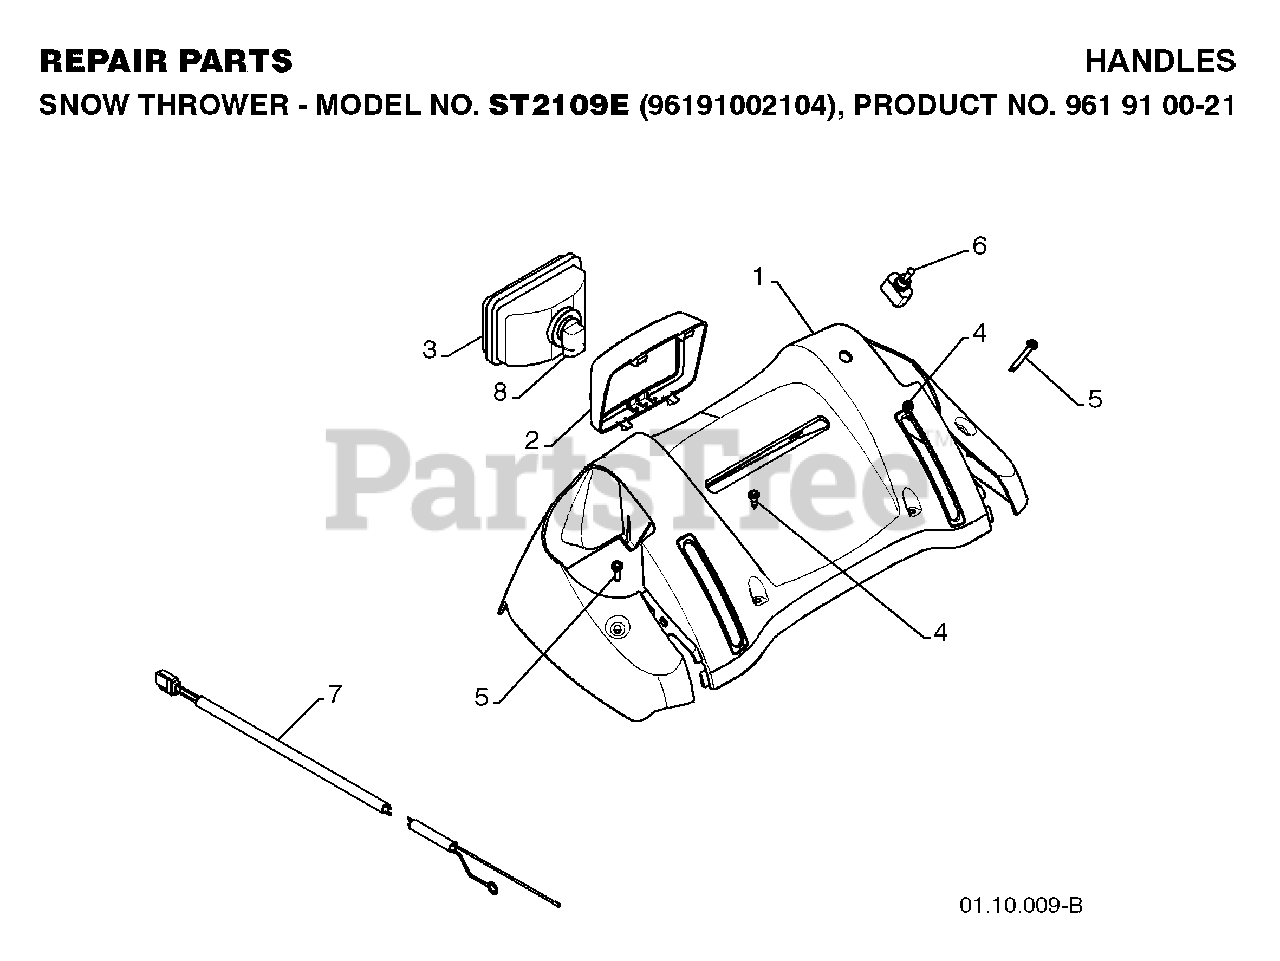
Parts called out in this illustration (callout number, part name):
1	CONSOLE, PANEL
2	BEZEL.HEADLIGHT.BLACK
3	HEADLIGHT, HALOGEN
4	SCREW, HEX HEAD, TAPPING
5	SCREW, HEX HD TAPPING #10-24 1
6	SWITCH.GRIP.HEATED
7	HARNESS.WIRE.LIGHT/GRIP.SNOW
8	BULB.HEADLIGHT.HALOGEN.
